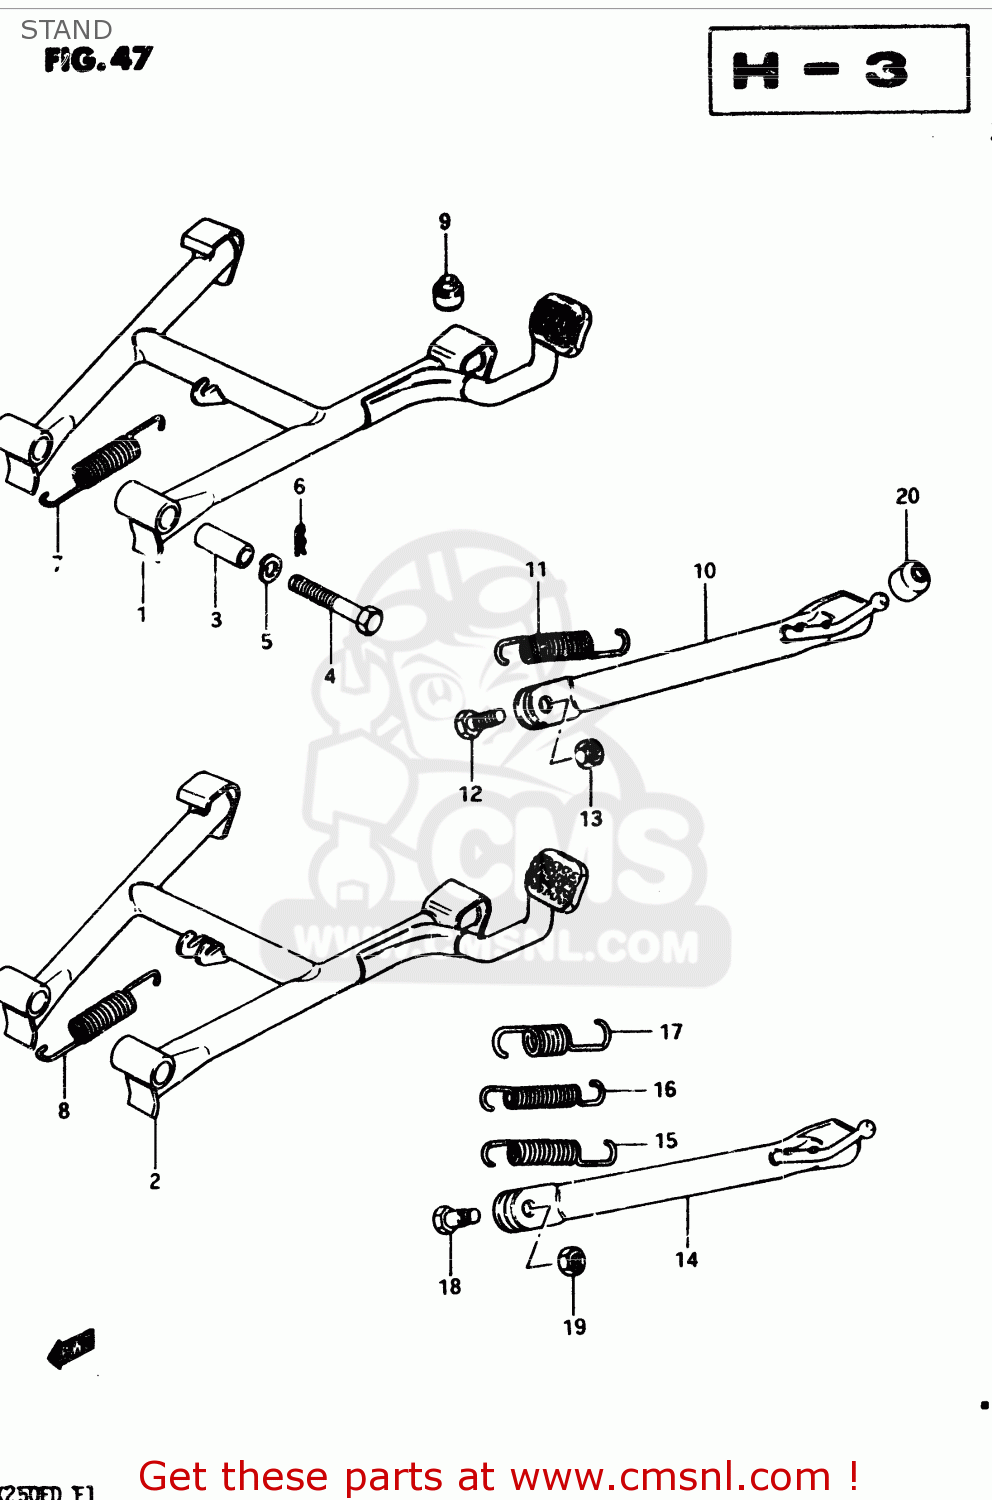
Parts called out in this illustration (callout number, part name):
1	STAND,CENTER
2	STAND, CENTER
3	SPACER(10X16X38.8)
4	BOLT
5	LOCK WASHER
6	CLIP
7	SPRING
8	SPRING
9	CUSHION
10	STAND,SIDE
11	SPRING
12	BOLT(10X30)
13	NUT
14	STAND, PROP
15	SPRING
16	SPRING
17	SPRING, OUTER
18	BOLT
19	NUT
20	CUSHION
